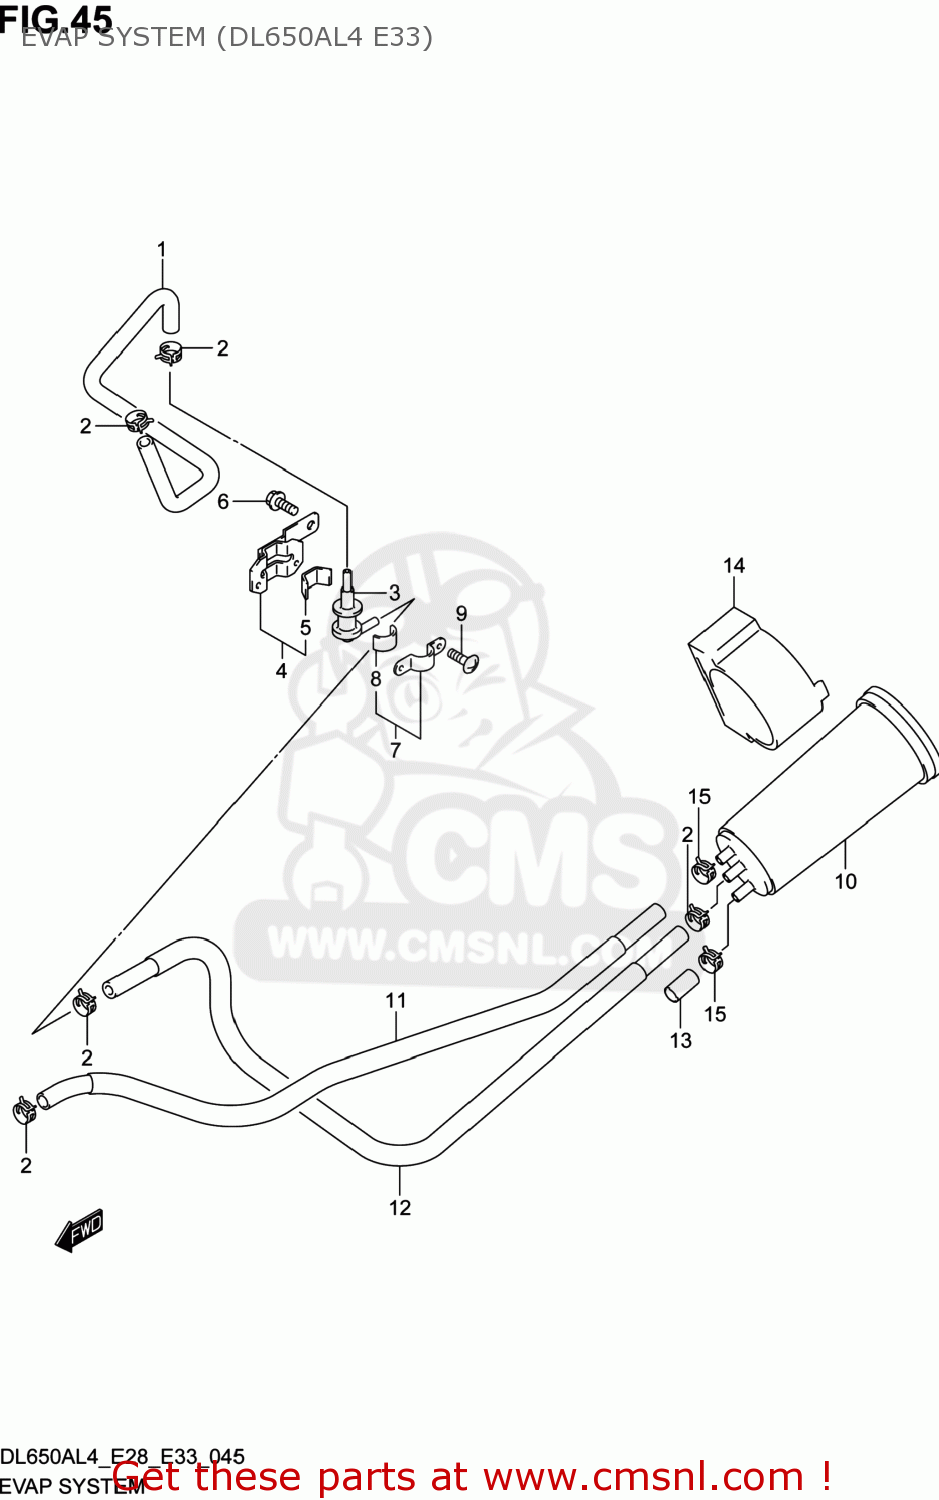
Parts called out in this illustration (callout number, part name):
1	HOSE,TANK & BREATHER VALVE
2	CLIP
3	VALVE,FUEL TANK BREATHER
4	PLATE,BREATHER VALVE
5	CUSHION
6	BOLT
7	PLATE,FUEL TANK BREATHER NO.2
8	CUSHION
9	SCREW
10	CANISTER ASSY,CHARCOAL
11	HOSE,CSTR PURGE
12	HOSE,CSTR SURGE
13	CAP,OD:11.5
14	CUSHION,CANISTER
15	CLIP
